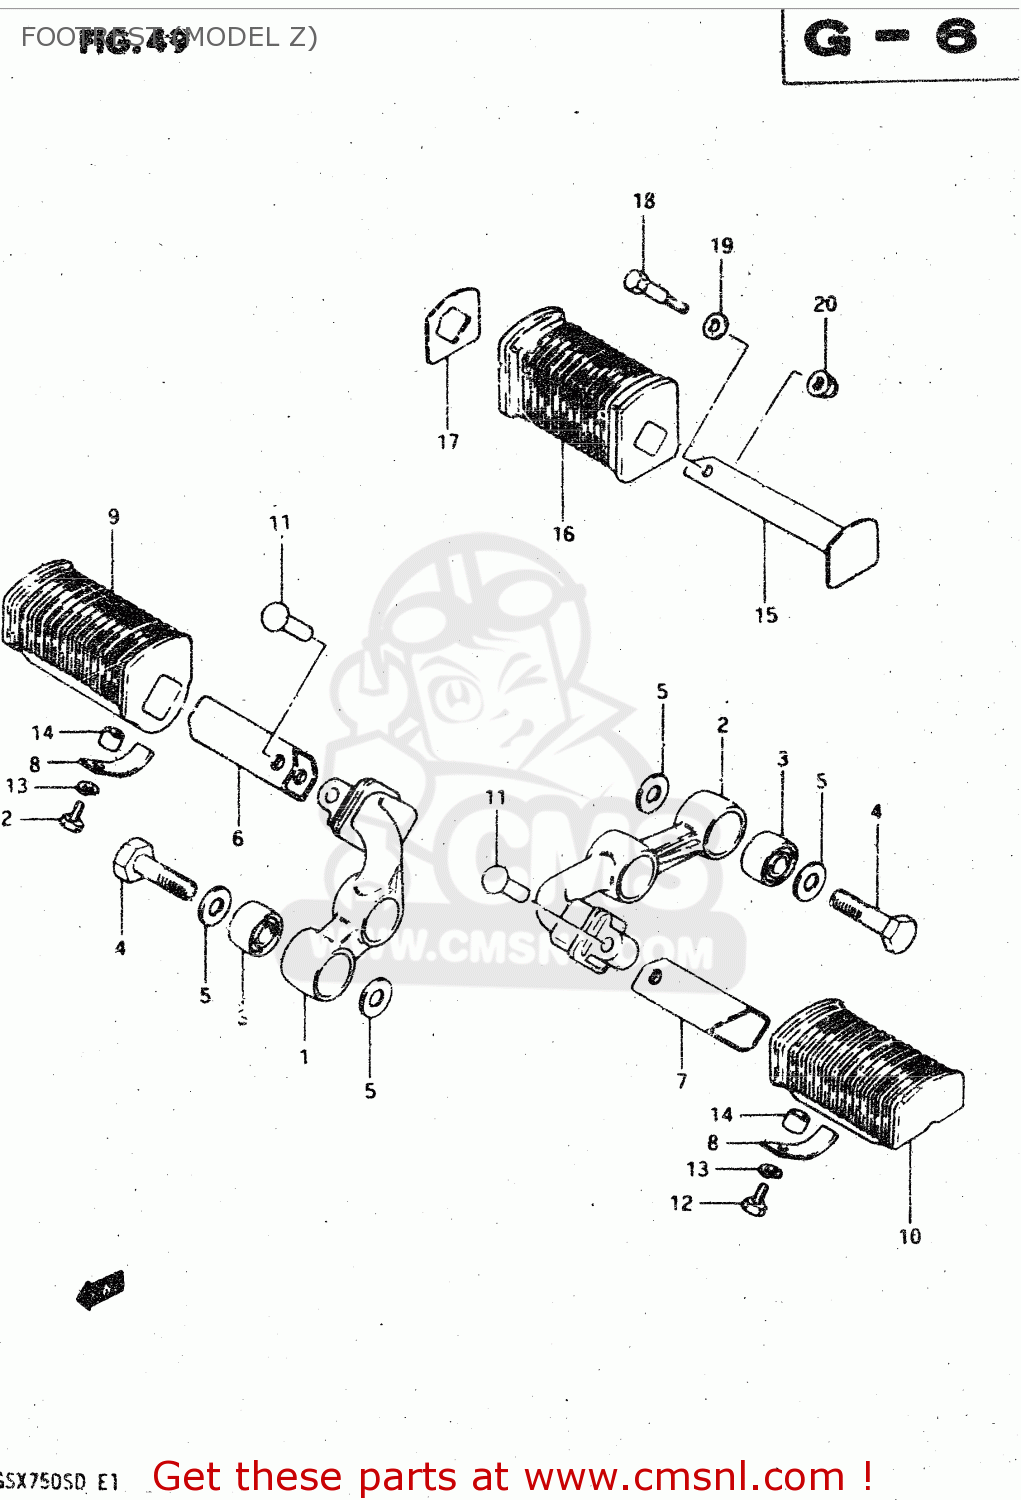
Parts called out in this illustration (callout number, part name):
1	BAR, FOOTREST RH
2	BAR, FOOTREST LH
3	BUSH
4	BOLT
5	WASHER
6	HOLDER, COVER RH
7	HOLDER, COVER LH
8	PLATE, FOOTREST STOPPER
9	RUBBER,FR FOOTREST,R
10	RUBBER,FR FOOTREST,L
11	RIVET
12	BOLT, UPPER
13	LOCK WASHER
14	SPACER(6.5X10.5X6.5)
15	BAR, RH
16	RUBBER,PILLION FOOTREST
17	WASHER,PILLION FOOTREST RUBBER
18	BOLT(6X40)
19	WASHER
20	NUT
